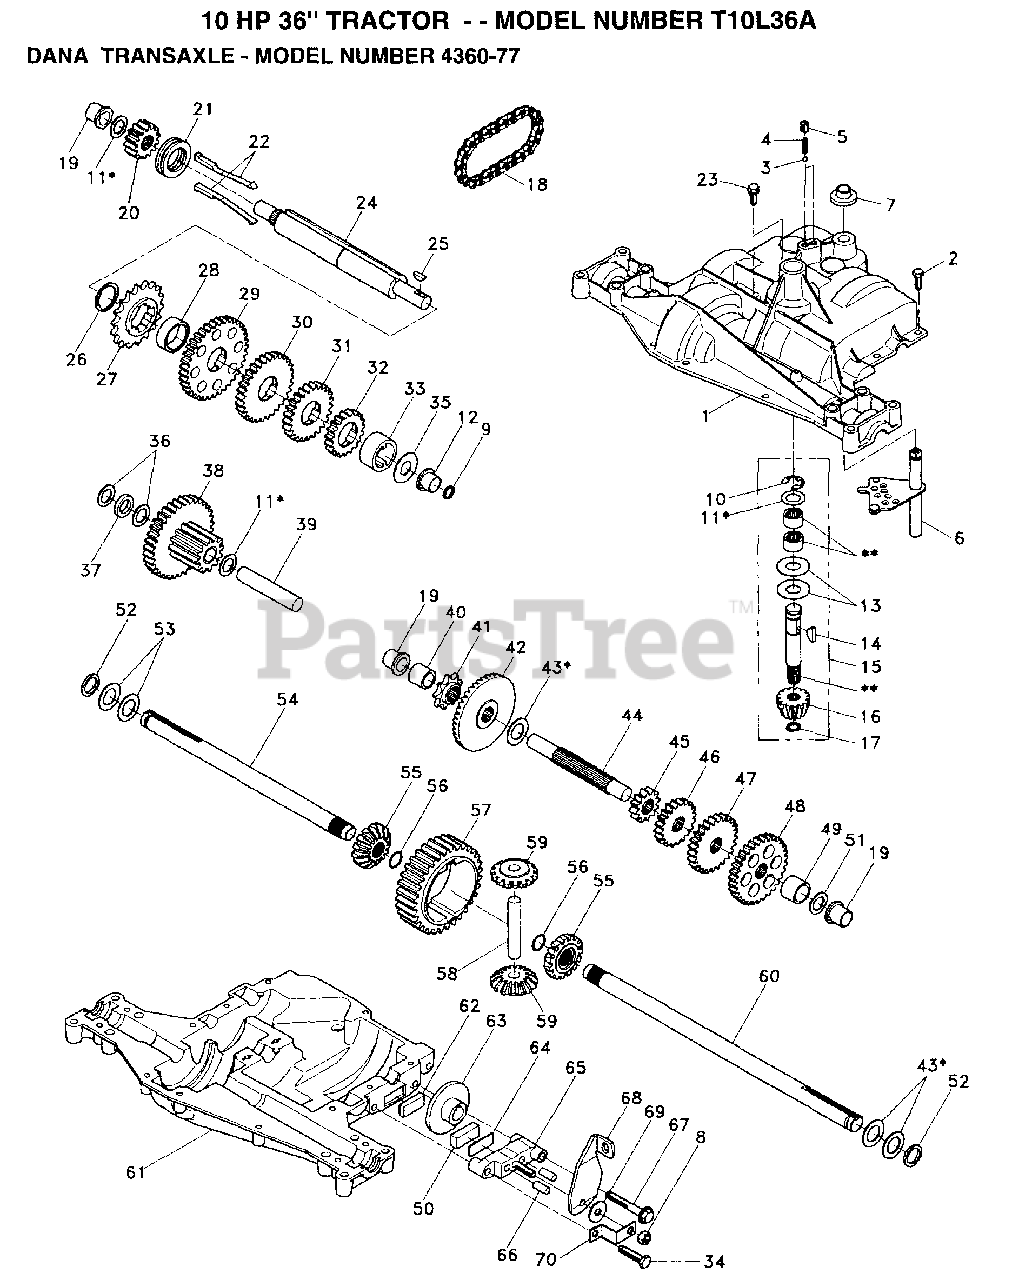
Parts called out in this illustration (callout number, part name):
1	HOUSING UPPER TRN
4	"SPRING, DETENT LT"
5	"SCREW, SET LT"
6	KIT SHIFTER ASM
7	SHIFTER BOOT
8	NUT.LOCK.5/16-24
9	SEAL OIL DANA5416
11	ASM KIT SHIM 4689
13	WASHER T
14	KEY WOODRUFF-DANA
15	AS KIT INPUT SHFT
16	PINION 14T T
17	"RING,RETAINING LT"
18	"CHAIN,24 PTCH LT"
19	BEARING.FLNG.5510
20	GEAR SPUR 14 TTH
21	COLLAR CLUTCH
22	ASM KIT CLTCH KEY
23	SCREW TAP W/SEAL
24	SHAFT INTERM DANA
25	WOODRUFF KEY
26	"RING,RETAINING LT"
27	SPROCKET 18T T
28	SPACER YT
29	GEAR SPUR 37 TTH
31	GEAR 25T LT
32	SPUR GEAR 19T
33	SPACER
34	"SCREW, TAPPING LT"
35	"WASHER, PLAIN LT"
36	WASHER 025
37	SPACER
38	ASSM GEAR COMB
39	SHAFT IDLER
40	SPACER T
41	SPROCKET 9T LT
43	ASM KIT SHIM
44	SHAFT T
45	GEAR SPUR 12 TTH
47	"GEAR, SPUR 25T LT"
48	"GEAR, SPUR 31T LT"
50	PUCK T
51	WASHER 060
52	NEOPRENE WASHER
53	WASHER 031
55	GEAR 15T T
56	"RING,RETAINING LT"
58	SHAFT T
59	GEAR 1ST T
61	HOUSING LOWER TNS
62	PUCK T
63	BRAKE DISC. T
64	SPACER LT
66	PIN T
69	WASHER LT
